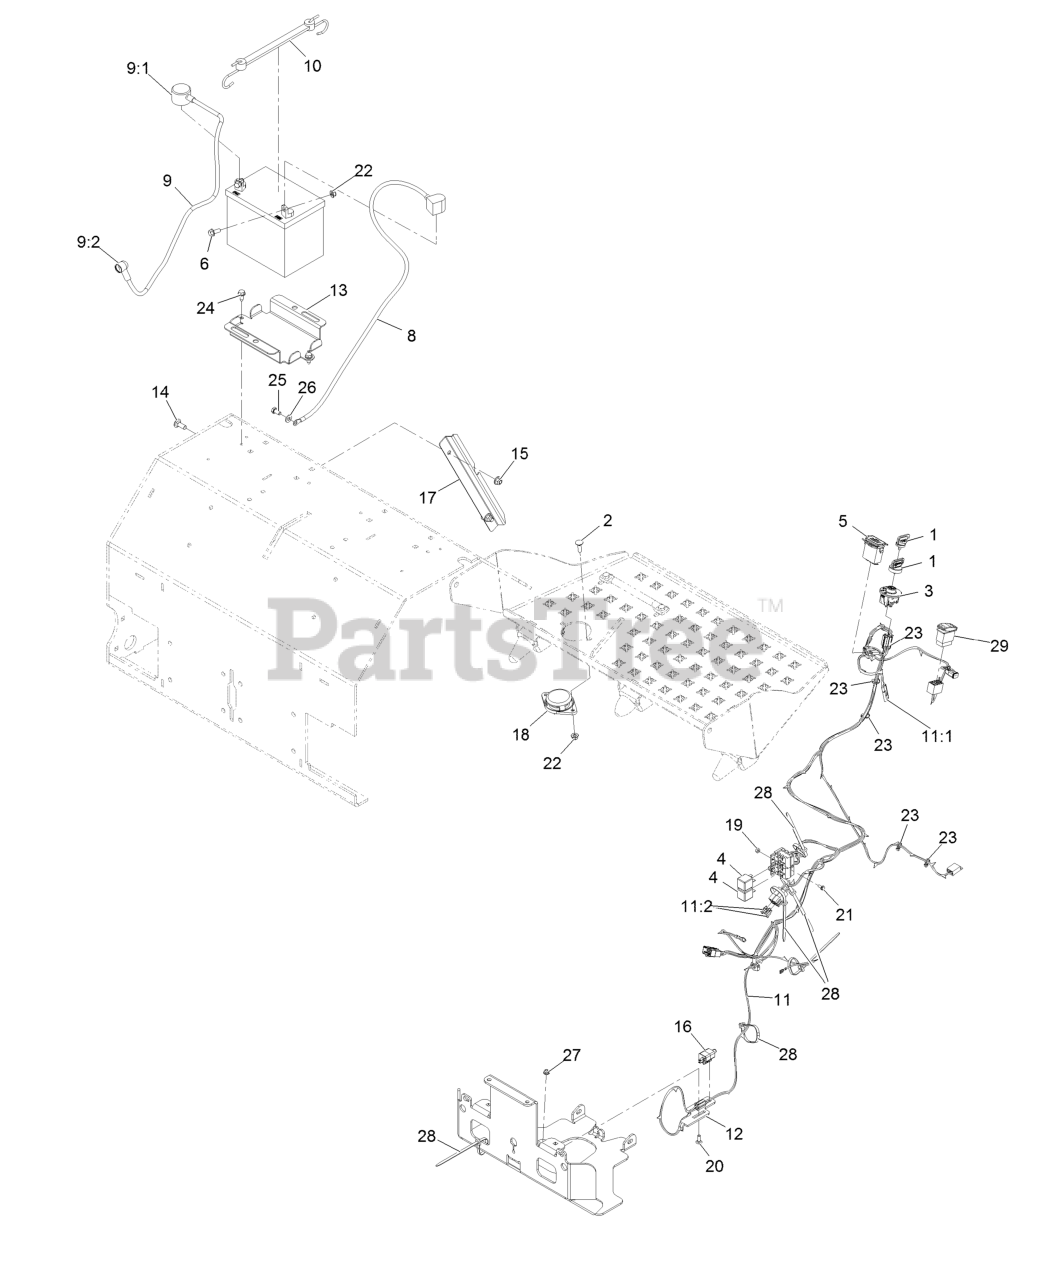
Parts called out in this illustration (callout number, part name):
1	Key-Ignition
1	Key-Exmark Logo
2	Bolt-Carriage 5/16-18 X 1
3	Switch-Ignition
4	Relay-12Vdc 40 Amp
5	Meter-Engine Hours
6	Screw-HH Flg 5/16-18 X 3/4
8	Cable-Battery, Black
9	Positive Battery Cable ASM
9:1	Insulator-Battery
9:2	Insulator-Solenoid
10	Holddown-Battery
11	Harness-Wire
11:1	Cap-Plug
11:2	Fuse-Blade Type, 20 Amp
12	Mount-Switch
13	Bracket-Battery
14	Bolt-Carriage 3/8-16 X 1
15	Nut-Nyloc 3/8-16 Flg
17	Guard-Harness
18	Switch-Seat
19	Nut-Nyloc #10-24
20	Bolt-Carriage 1/4-20 X 3/4
21	Screw-HWH
22	Nut-Nyloc 5/16-18 Flg
23	Tie-Cable 5 1/2 (Small)
24	Screw-HWH 5/16-18 X 3/4 Tf
25	Screw-HH M8-1.25 X 16Mm
27	Nut-Nyloc 1/4-20 Flg
28	Tie-Cable 7 15/16 (Large)
